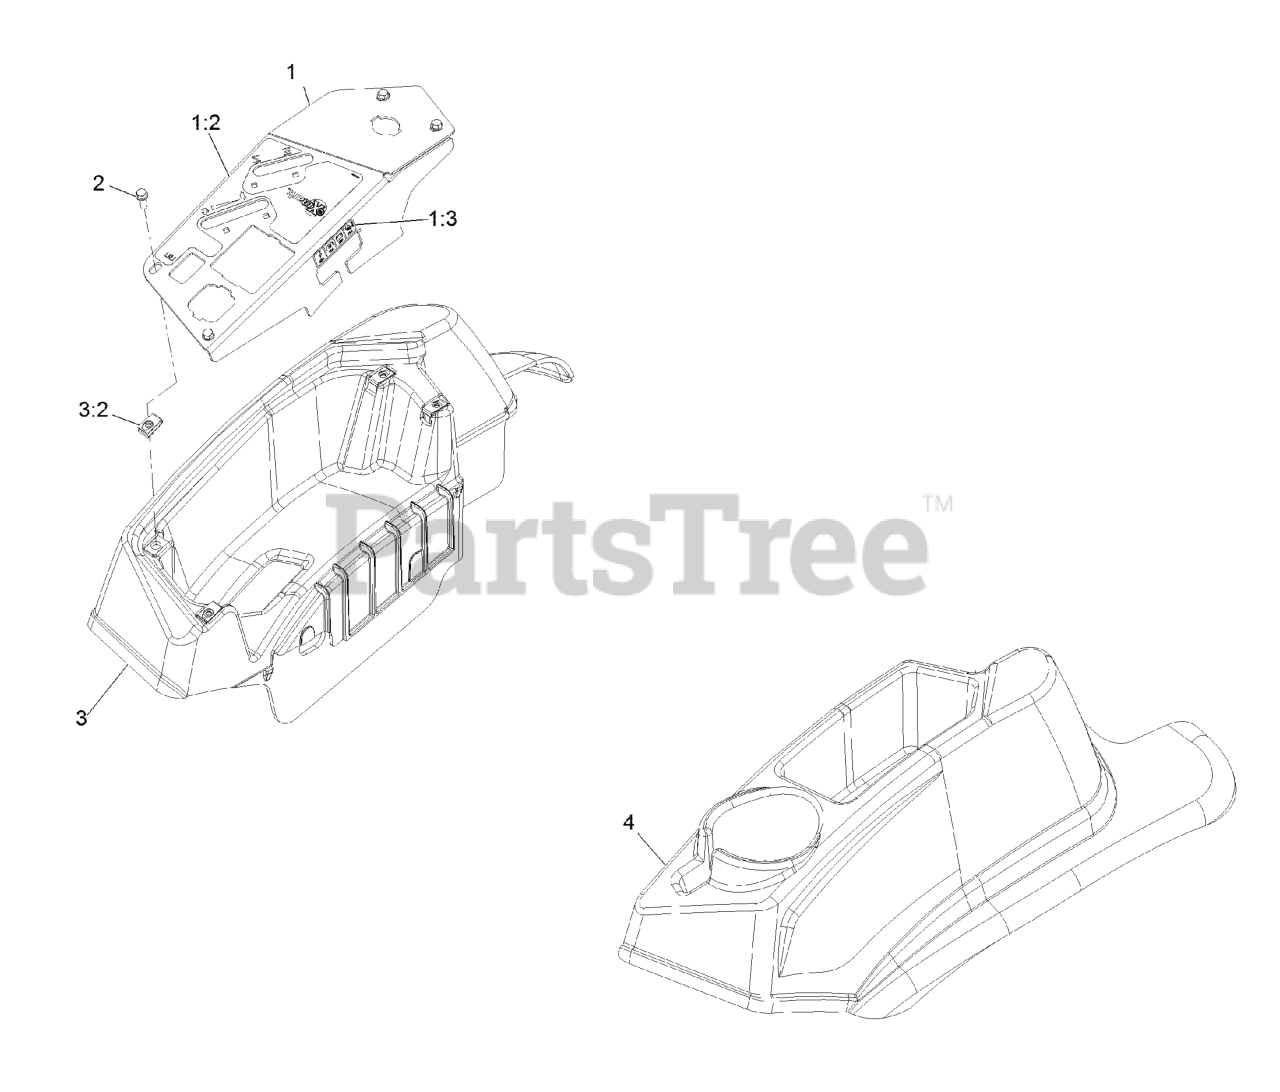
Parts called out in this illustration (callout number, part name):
1	ASM-PANEL, CONTROL W/DECAL
1:2	DECAL-CONTROL PANEL NON-EFI
1:3	DECAL-FUSES
2	SCREW-HWH
3	CONSOLE,RH AS ASM
4	CONSOLE, LH AS
